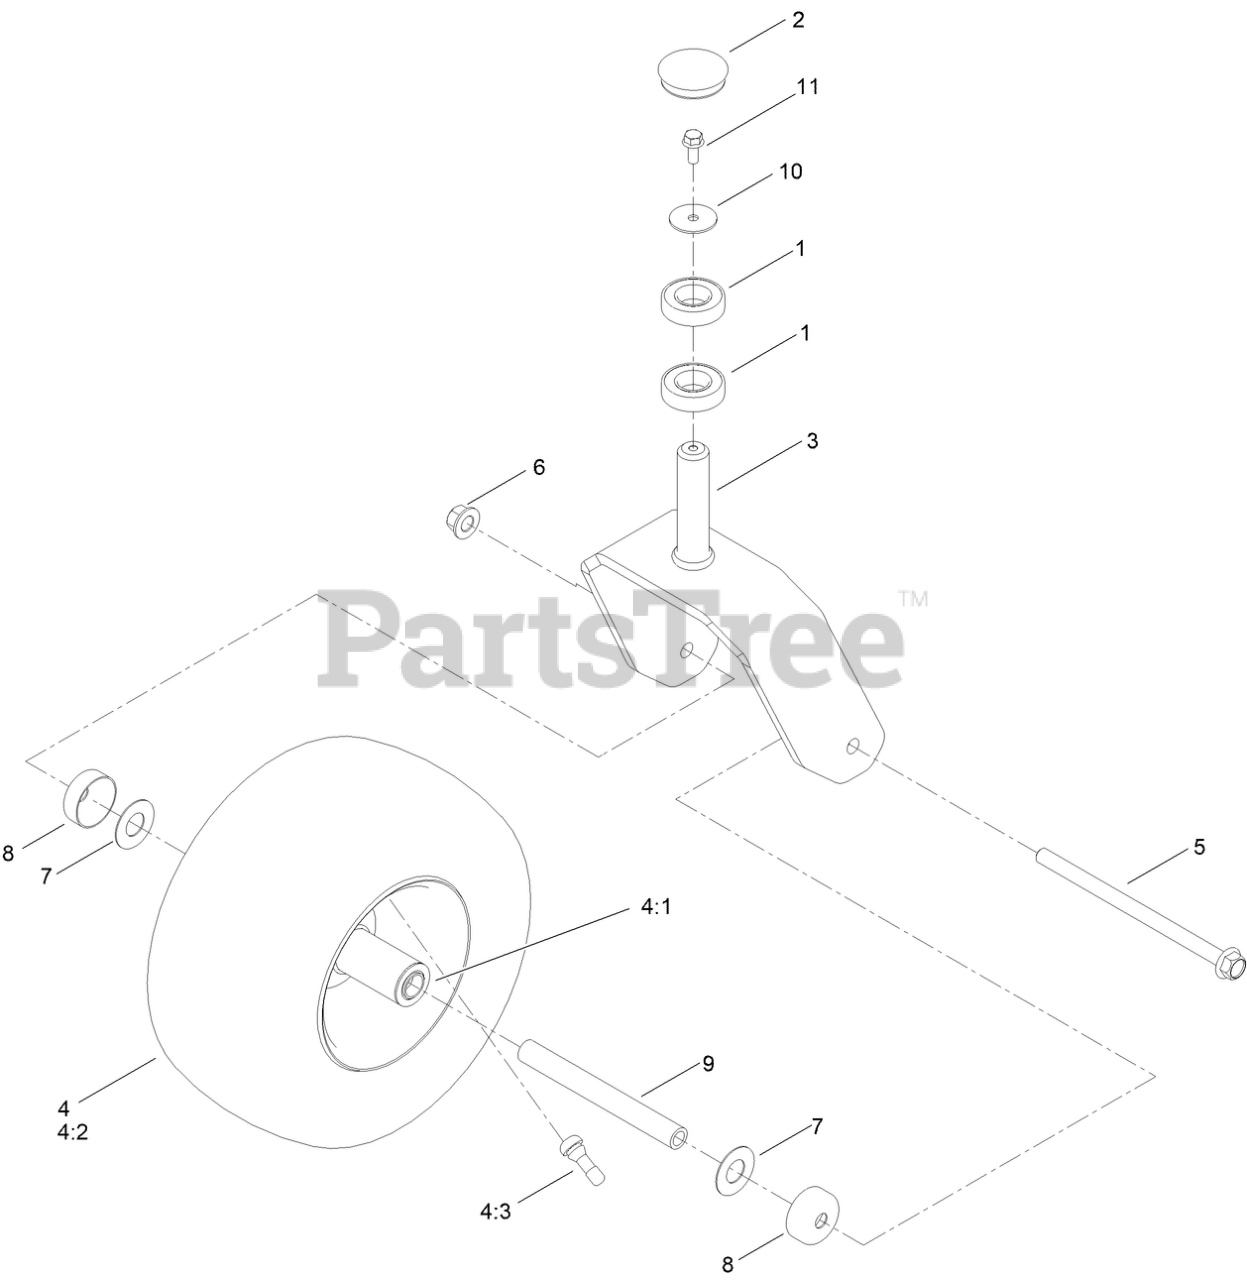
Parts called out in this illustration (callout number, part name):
1	BEARING-BALL
2	CAP,GREASE
3	FORK ASM [BLK-TXT]
4	CASTER TIRE ASM 13X6.5-6
4:1	WHEEL W/BEARINGS
4:2	TIRE 13X6.5-6
5	SCREW-HHF
6	NUT-LOCK
7	WASHER
8	GUARD-SEAL
9	SPANNER-WHEEL
10	WASHER-FLAT
11	SCREW-HHF
